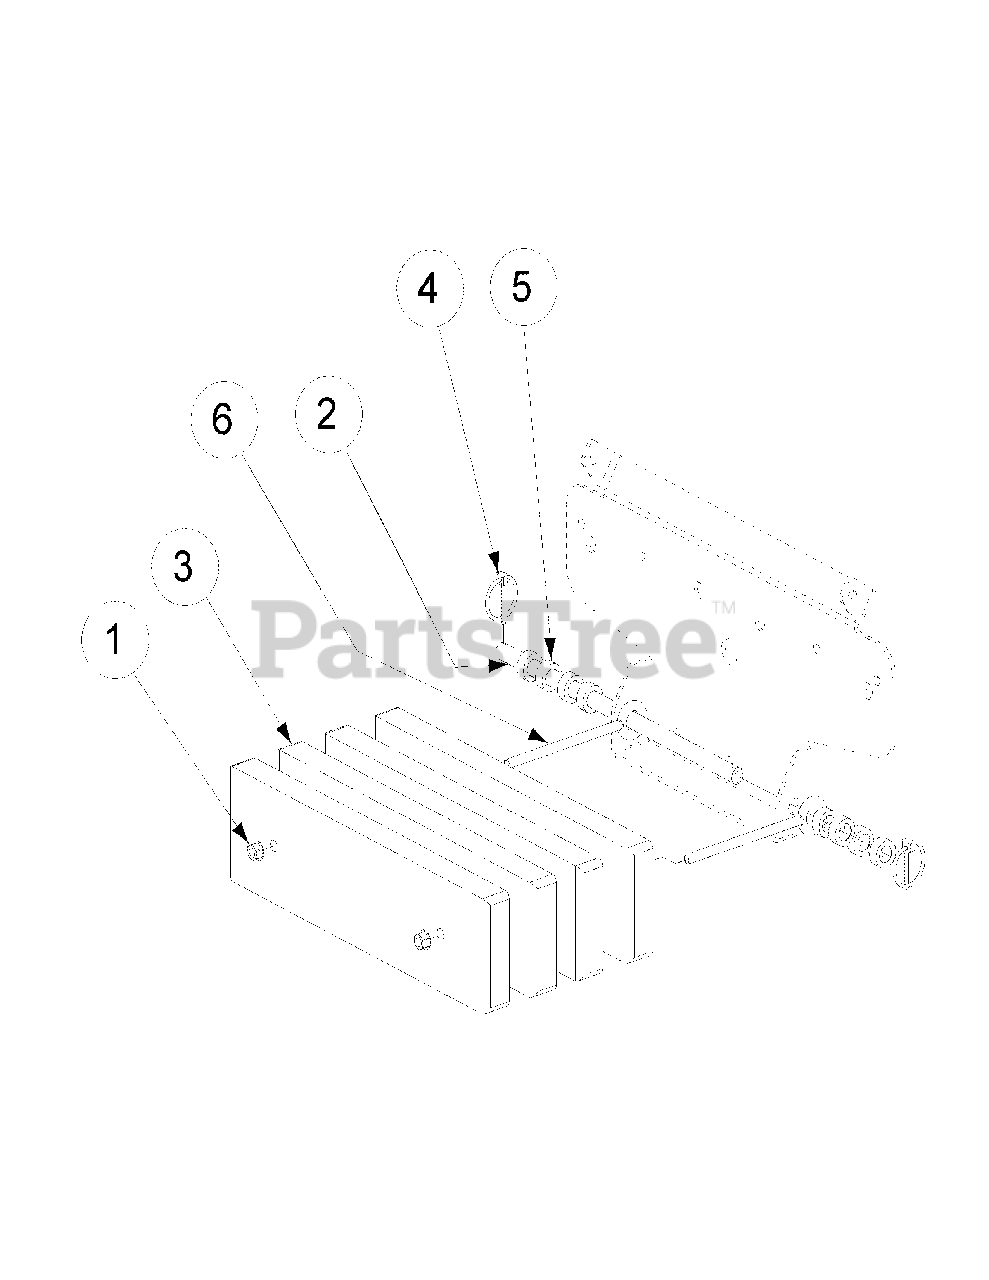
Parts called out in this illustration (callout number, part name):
1	Flange Lock Hex Nut, 3/8-16
2	Front Lift Link, Rod Mount
4	Linch Pin, 3/16 Dia.
5	Spacer, .630 x 1.06 x .440
6	Eyebolt, 3/8-16, Forged Steel
